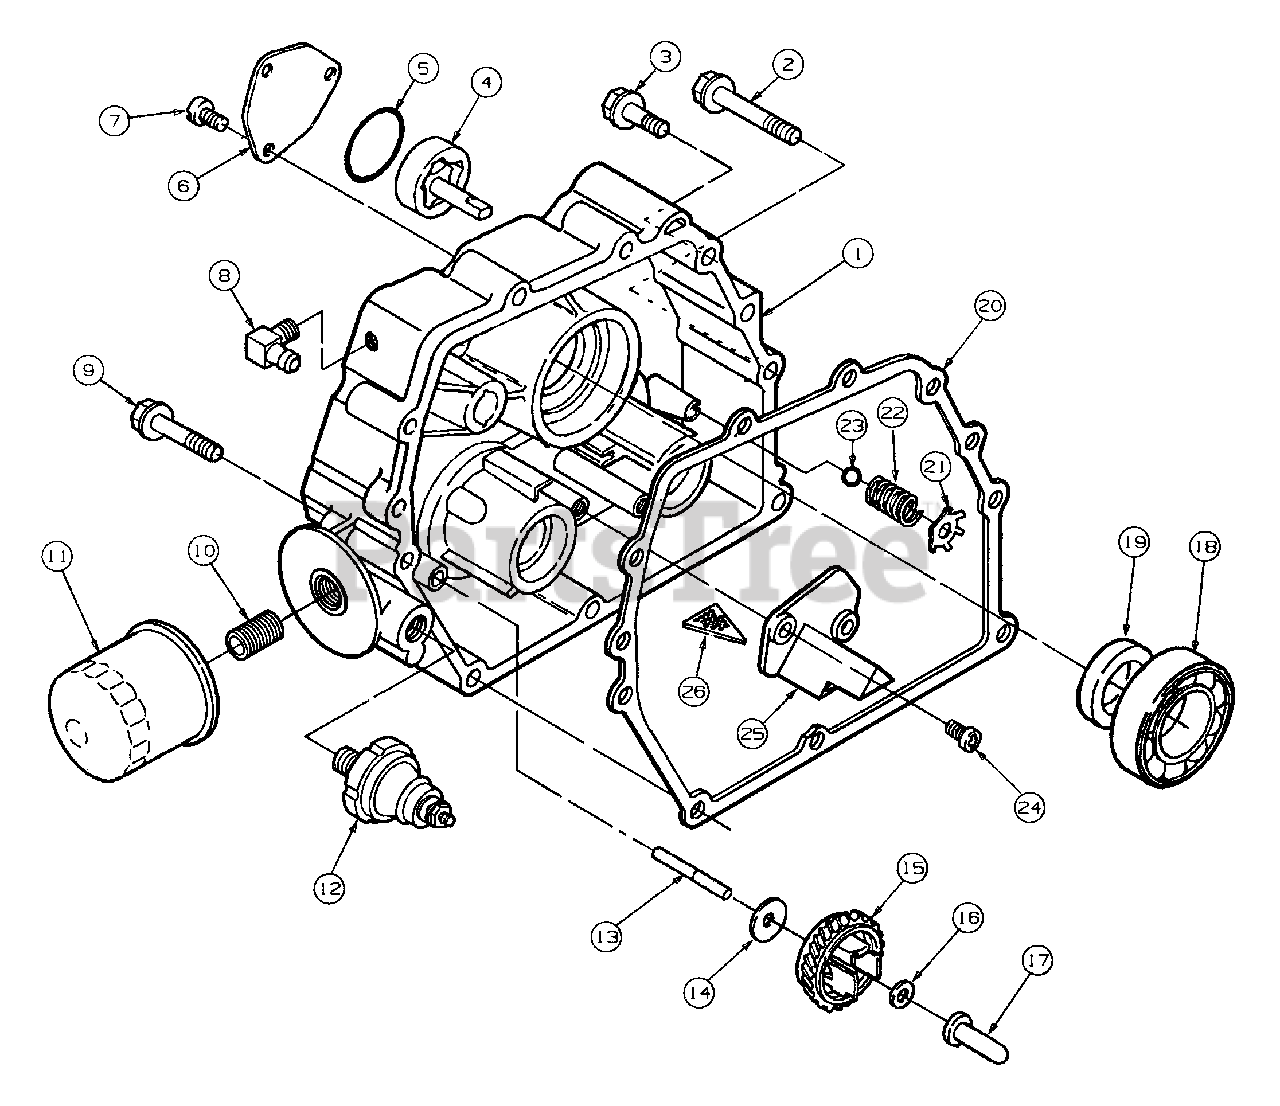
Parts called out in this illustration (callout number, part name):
2	Screw, Hex Hd, TT, M8x1.25x 70
3	Screw, Hex Hd, TT, M8x1.25x 35
6	Cover, Oil Pump
7	Screw, Torx Pan Hd, M6 x 1 x 14
8	Elbow, 90° Hose
9	Screw, Hex Hd TT, M8 x 1.25x 50
10	Adapter, Oil Filter
12	Switch, Oil Pressure
13	Shaft Governor
14	Washer, Flat, Special
15	Gear, Gov
16	Retainer, Governor Gear
17	Sleeve, Governor
18	Bearing, Crankshaft
19	Seal, Crankshaft Oil
20	Gasket, Gearcase
21	Ring, Retaining
22	Spring, Relief Valve
23	Ball, Steel, 7.5mm OD
24	Screw, Torx Pan Hd, M6 x 1 x 14
25	Tube, Oil Pickup
26	Screen Oil Pickup
